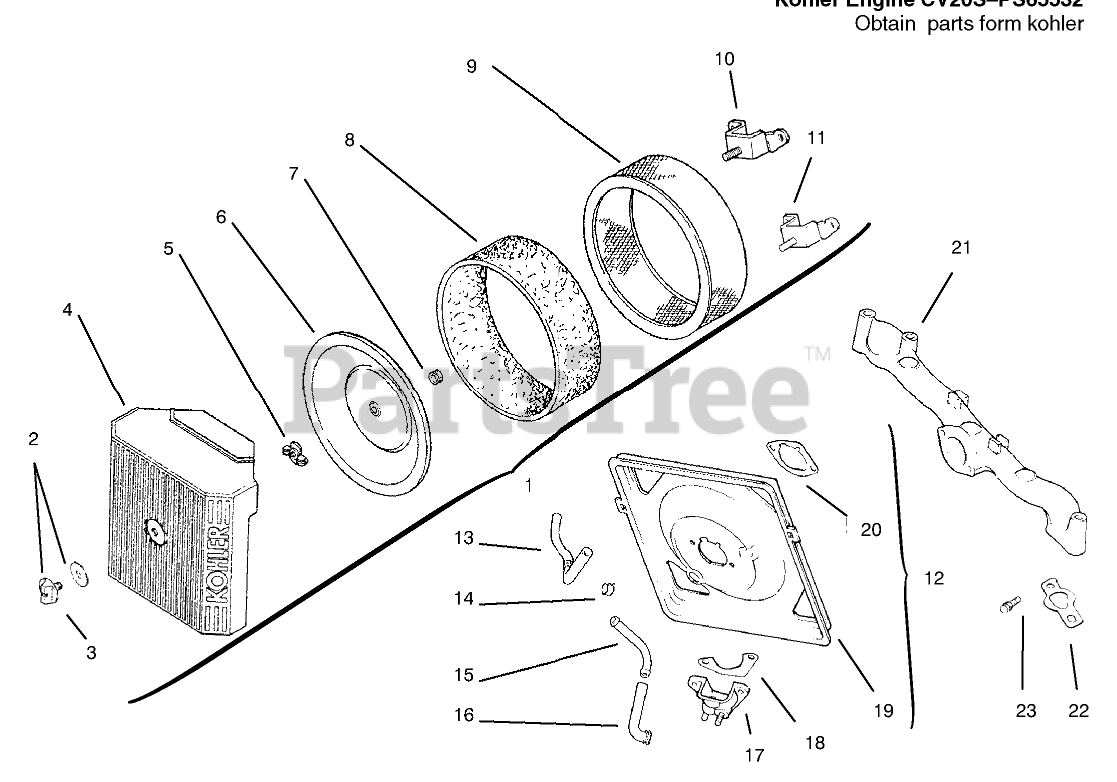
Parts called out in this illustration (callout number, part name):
1	Kit-A/C Cover INC 2-4
2	Spring-Latch
3	Latch-Lever
4	Pin-Latch Lever
5	Wingnut
6	Seal, insert
7	Cover-Inner AirCleaner
8	Bement-Precleaner
9	Bement-Air Cleaner
10	Cup-Fuel Spitback
11	Gasket-Fuel Spitback
12	Base-Air Cleaner
13	Gasket-A/C Base
14	Manifold-Intake
15	Gasket-Intake, Manifold
16	Screw
